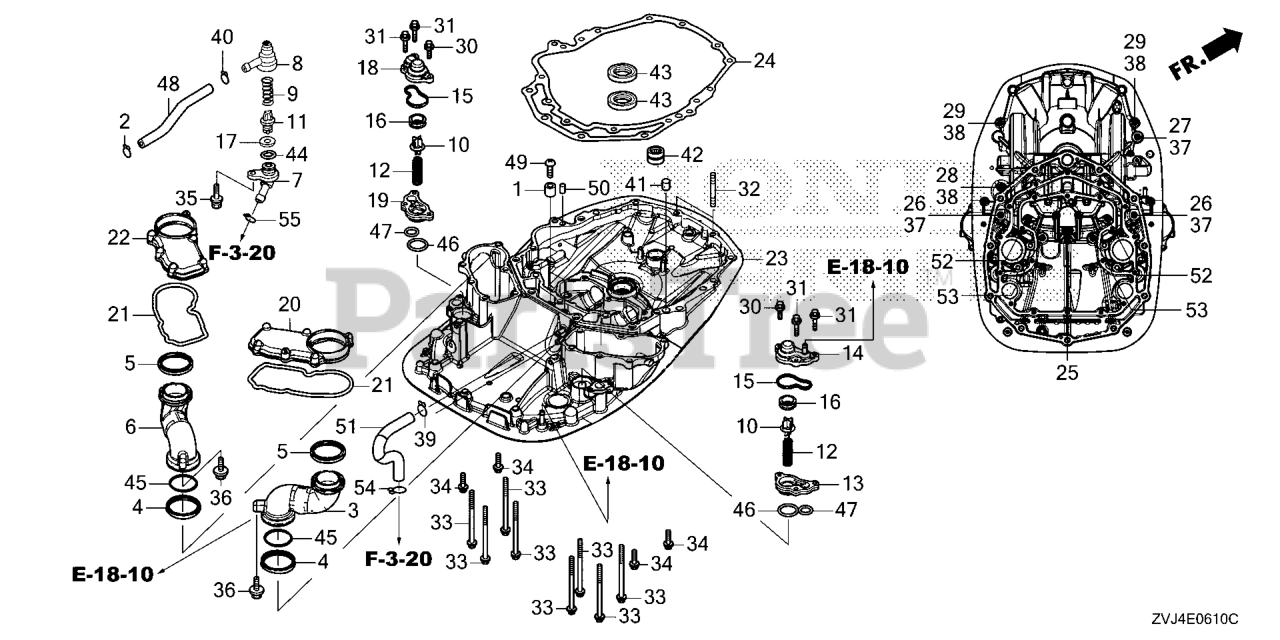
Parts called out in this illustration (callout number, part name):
1	METAL, ANODE
2	CLIP, TUBE (ENGINE NO.)
3	GUIDE, R. EX. *TGRAY* (GRAY)
4	SEAL, EX. GUIDE
5	SEAL B, EX. GUIDE
6	GUIDE, L. EX. *TGRAY* (GRAY)
7	COVER, FLUSH VALVE *NH8* (DARK GRAY)
8	CASE, FLUSH VALVE
9	SPRING, FLUSH VALVE
10	VALVE, RELIEF
11	VALVE, FLUSH
12	SPRING, RELIEF VALVE
13	SPACER, R. RELIEF VALVE *TGRAY* (GRAY)
14	COVER, R. RELIEF VALVE
15	GASKET, RELIEF VALVE COVER
16	GASKET, RELIEF VALVE
17	GASKET, FLUSH VALVE
18	COVER, L. RELIEF VALVE
19	SPACER, L. RELIEF VALVE *TGRAY* (GRAY)
20	COVER, R. WATER JACKET
20	COVER, W/J R
21	GASKET, WATER JACKET COVER
22	COVER, L. WATER JACKET
22	COVER, W/J L
23	CASE, MOUNT *NH8* (DARK GRAY)
23	CASE COMP *NH8*
24	GASKET, MOUNT CASE
25	BOLT, FLANGE (10X120) (SATO)
26	BOLT, HEX. (12X120)
27	BOLT, HEX. (12X65)
28	BOLT, HEX. (10X85)
29	BOLT, HEX. (10X60)
30	BOLT, FLANGE (6X22)
31	BOLT, FLANGE (6X32)
32	BOLT, STUD (10X45)
32	BOLT 2, STUD (10X45)
33	BOLT, FLANGE (8X120)
34	BOLT, FLANGE (8X30)
35	BOLT-WASHER (6X29)
36	BOLT, FLANGE (6X40)
37	WASHER, PLAIN (12MM)
38	WASHER, PLAIN (10MM)
39	CLAMP, TUBE (D10.5) (ENGINE NO.)
40	CLIP, TUBE (B12.5)
41	PIN, DOWEL (14X15)
42	BEARING, NEEDLE (20X28X13) (SOLID)
43	SEAL, WATER (22X35X7)
44	O-RING (16MM)
45	O-RING (49.4X3.1)
46	O-RING (33.5X2)
47	O-RING (23.5X2)
48	TUBE, FLUSH VALVE
49	SCREW, PAN (5X16)
50	PIN B, DOWEL (10X16)
51	TUBE, WATER
52	BOLT, FLANGE (10X70)
53	BOLT, FLANGE (12X120)
54	CLIP, TUBE (B1 11)
55	CLIP, TUBE (B12.5)
55	CLIP B1, TUBE
